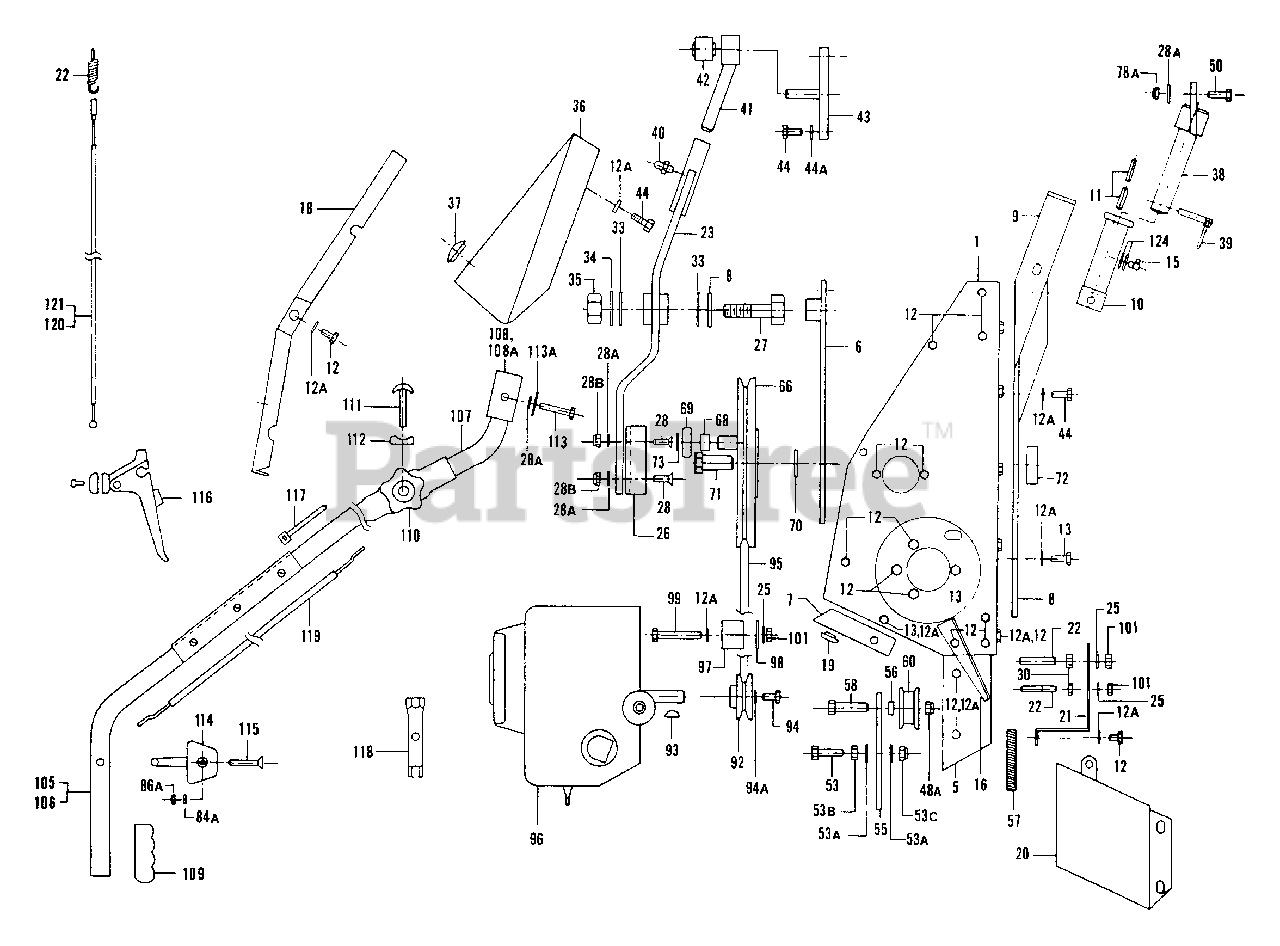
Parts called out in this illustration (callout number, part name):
1	Frame Assembly
5	Plate-Engine Mount
6	Plate-Bottom Reinforcement
7	Frame Hood-Rear
8	Washer, Drive Arm, Bottom
9	Cutter Bar Weldment
10	Cutter Bar Holder Kit
11	Roll Pin Set-6 x 20
12	Screw-HHM8 x 12
12A	Washer
13	Screw-HHM8 x 16
15	Grease Fitting-90° M6 x 100
16	Grass Shield-Wheel-RH
18	Hood w/Logo Decal
19	Plastic Plug
20	Cover-Drive Belt
21	Cover-Cutter Bar Belt
22	Rod-Belt Disengagement
23	Drive Arm Assembly
25	Star Washer
26	Channel-Drive Arm
27	Drive Arm Pivot Bolt M16
28	Screw FHC 90° M8 x 30 Class 10.9
28A	Washer
28B	Nylon Nut M8 Class 10.9
30	Nylon Nut M8
33	Snap Ring
34	Washer, Drive Arm, Top
35	Nut-Nylon M16
36	Grass Shield w/Decal
37	Plastic Plug-Grass Shield
38	Mounting Shaft-Cutter Bar
39	Retaining Clip-M8 x 40
40	Grease Fitting-M6 x 100
41	Drive Socket
42	Bushing-Sickle Drive
43	Mount-Cutter Bar
44	Screw-HHM8 x 20
44A	Washer
48A	Nylon Nut
50	Screw-M8 x 25
53	Screw-HHM10 x 35
53B	Nut-HM10
53C	Nut-Nylon-HM10
55	Clutch Plate Blade
56	Bushing-Idler
57	Spring-Blade Engagement
58	Screw-HHM12 x 45
66	Flywheel Blade w/Bng. Kit
68	Bushing-Flywheel
69	Convex Bearing
70	Washer-Flywheel
71	Screw-M20-Flywheel
72	Nut-Flywheel
73	Circlip-Flywheel
78A	Nylon Nut
84A	Washer
86A	Nylon Nut
92	Pulley-Cutter Bar
93	Key-Woodruff (Engine Pulley)
94	Screw-3/8-24 HH
95	V-Belt-Cutter Bar
96	Engine-3.5 HP Briggs & Stratton
99	Screw-HHM8 x 70
101	Nut-M8
105	Handlebar w/Decals & Grips
106	Upper Handlebars w/Decals & Grips
107	Lower Handlebars
108	Rubber Tube-Handlebar R/H
108A	Rubber Tube-Handlebar L/H
109	Grip-Handlebar
110	Knob-Handlebar
111	Bolt-Handlebar
112	Lock Clamp-Handlebar
113	Screw-HHM8 x 55
113A	Washer
114	Throttle Control w/Decal
115	Screw M6 x 45
116	Handlebar Lever-Control
117	Tie Strap
118	Wrench-Spark Plug
119	Throttle Cable
120	Cable-Cutter Bar
121	Cable-Wheel Drive
122	Spring-Cable-Wheel Drive
124	Washer
